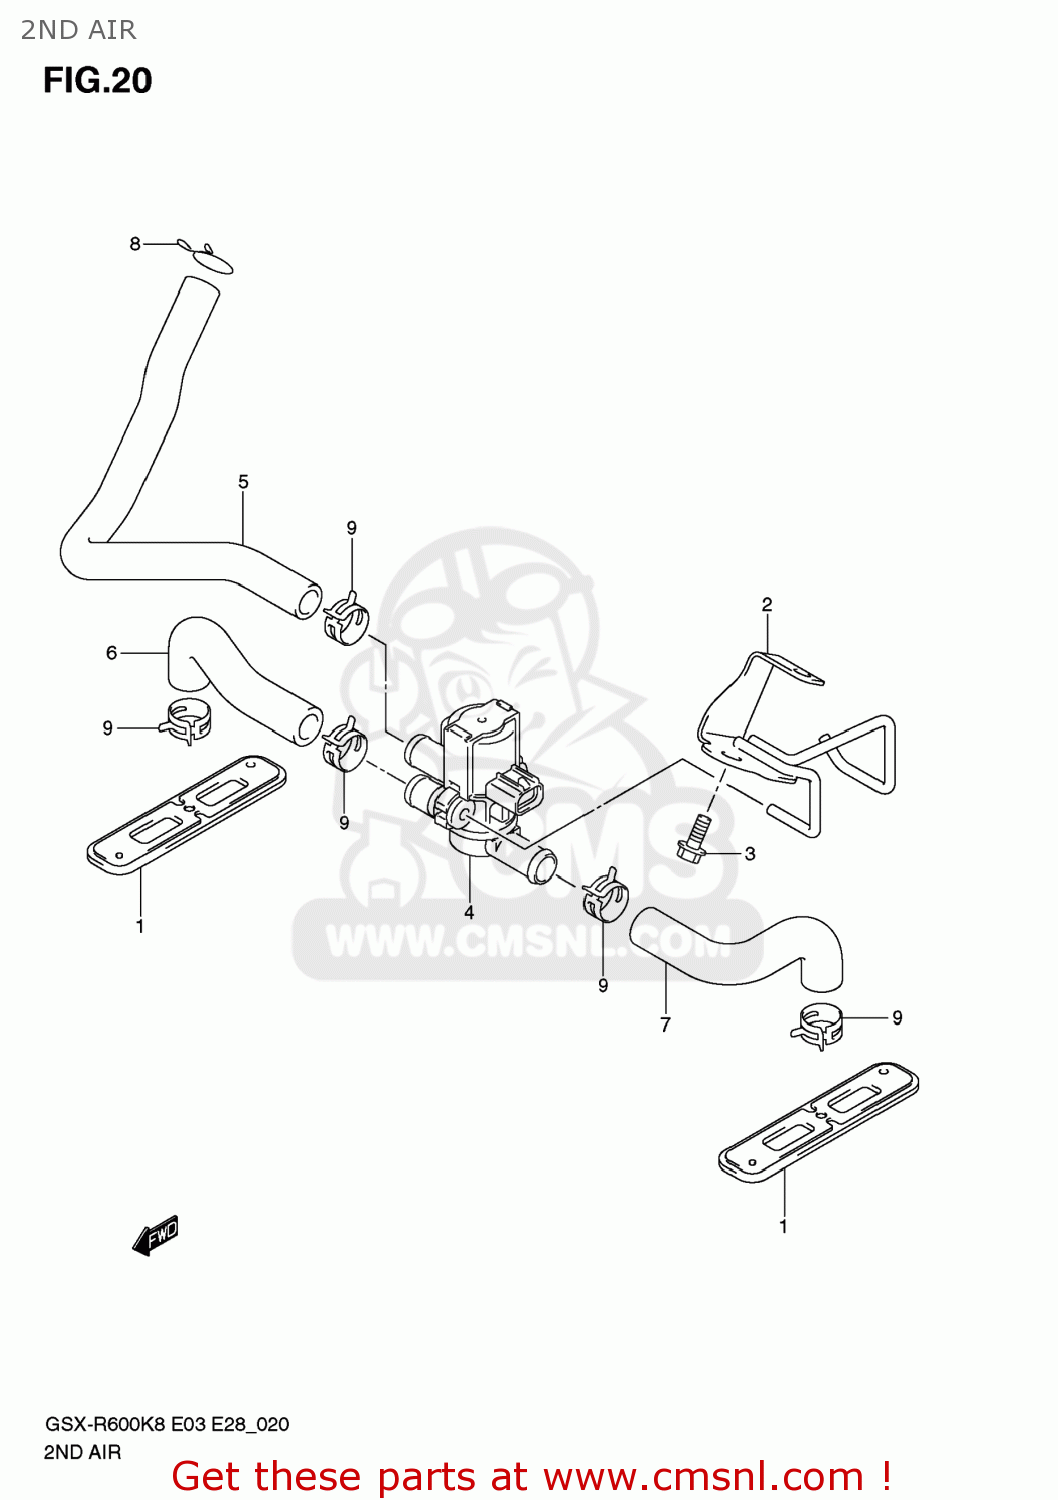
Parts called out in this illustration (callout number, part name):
1	VALVE ASSY,2ND AIR REED
2	BRACKET,2ND AIR VALVE
3	BOLT
4	VALVE ASSY,AIR CUT
5	HOSE,2ND AIR CLEANER
6	HOSE,2ND AIR VALVE,R
7	HOSE,2ND AIR VALVE,L
8	CLIP
9	CLIP
